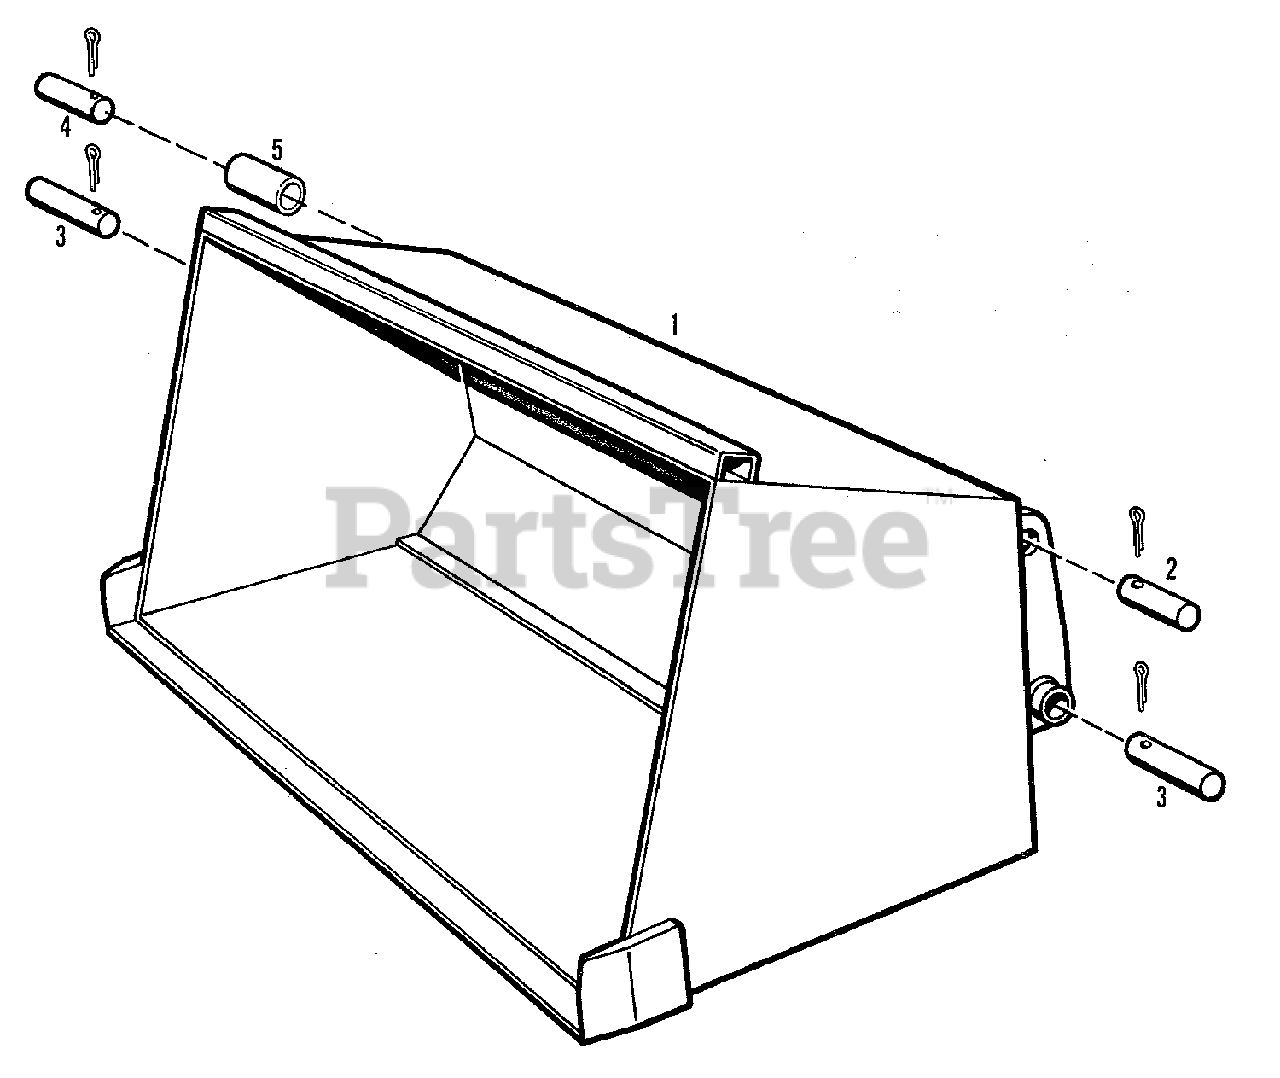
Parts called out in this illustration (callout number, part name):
1	BUCKET ASSEMBLY, Material
2	PIN, Attaching
2	PIN, Cotter, 1/4 x 2
3	PIN, Attaching
3	PIN, Cotter, 1/4 x 2
4	PIN, Attaching
4	CAPSCREW, 3/8NC x 3/4
4	WASHER, Plain, 3/8 x 7/8 x 14 Ga.
4	LOCKWASHER, 3/8
4	PIN, Cotter, 1/4 x 2
5	BUSHING, Pin
